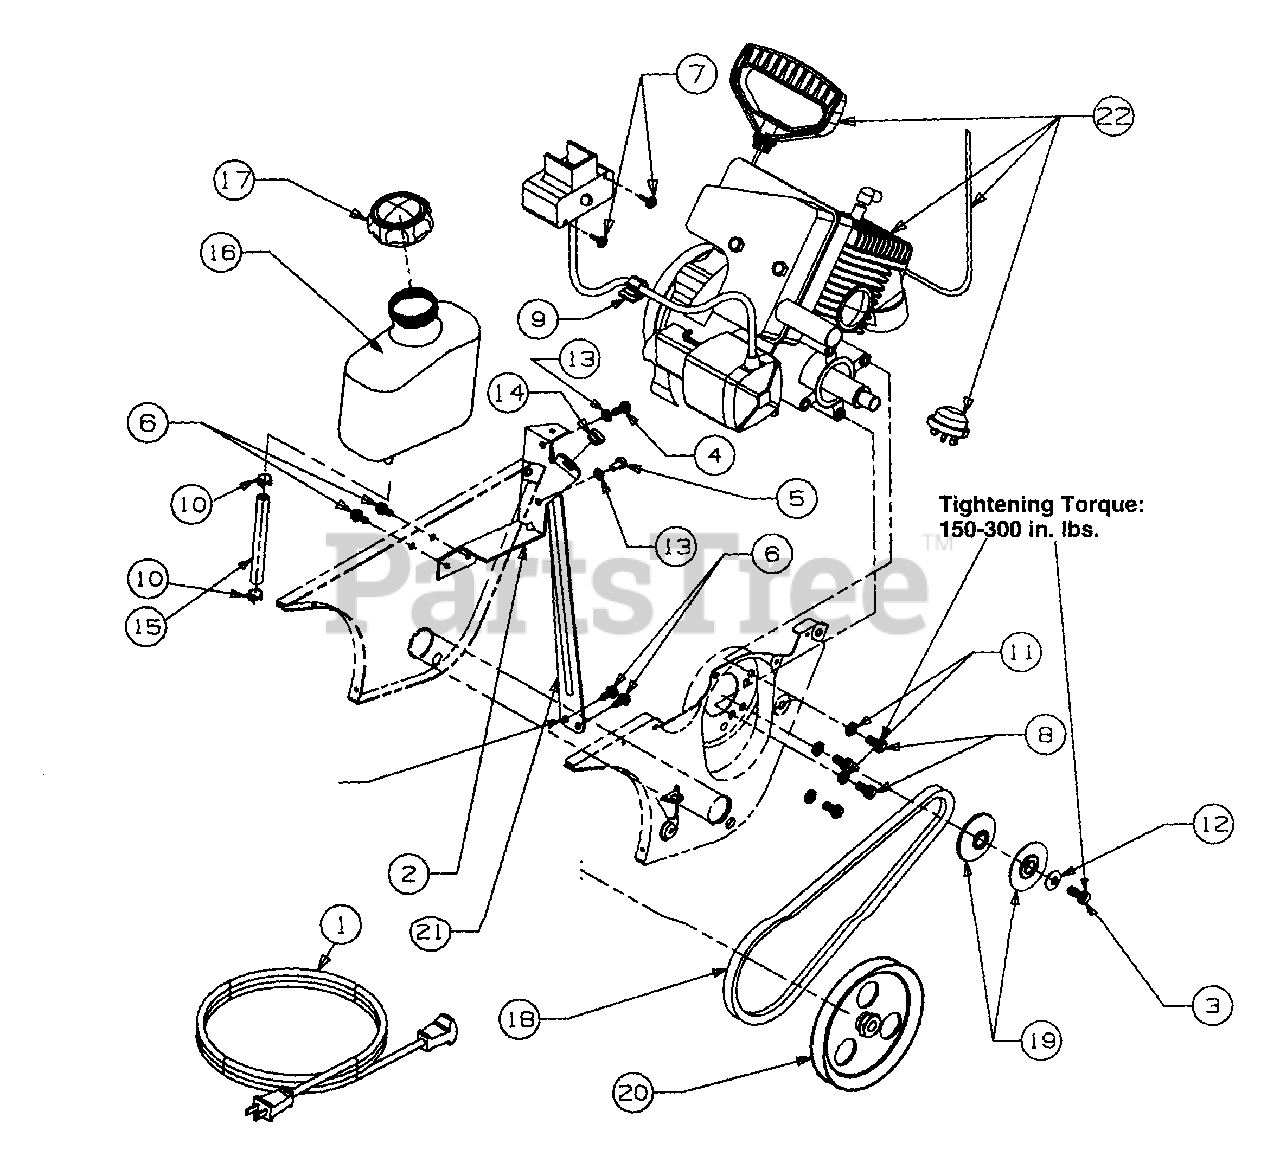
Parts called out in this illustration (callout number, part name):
1	Cord - Extension 110V3M 2 Prong
2	Bracket - Support Fuel Tank
3	Screw - Hex Cap
4	Screw - Hex Cap
5	Screw - Hex
6	Screw - Washer
7	Screw - Hex
8	Screw - Hex Cap
9	Clamp - Mounting
10	Clamp - Hose
11	Washer - Lock
12	Washer - Bell
13	Washer - Lock
14	Bushing - Plastic
15	Hose - Fuel Line 16"
16	Tank - Fuel 2 Qt.
17	Cap - Fuel
18	V-Belt
19	V-Pulley Half
20	Pulley
